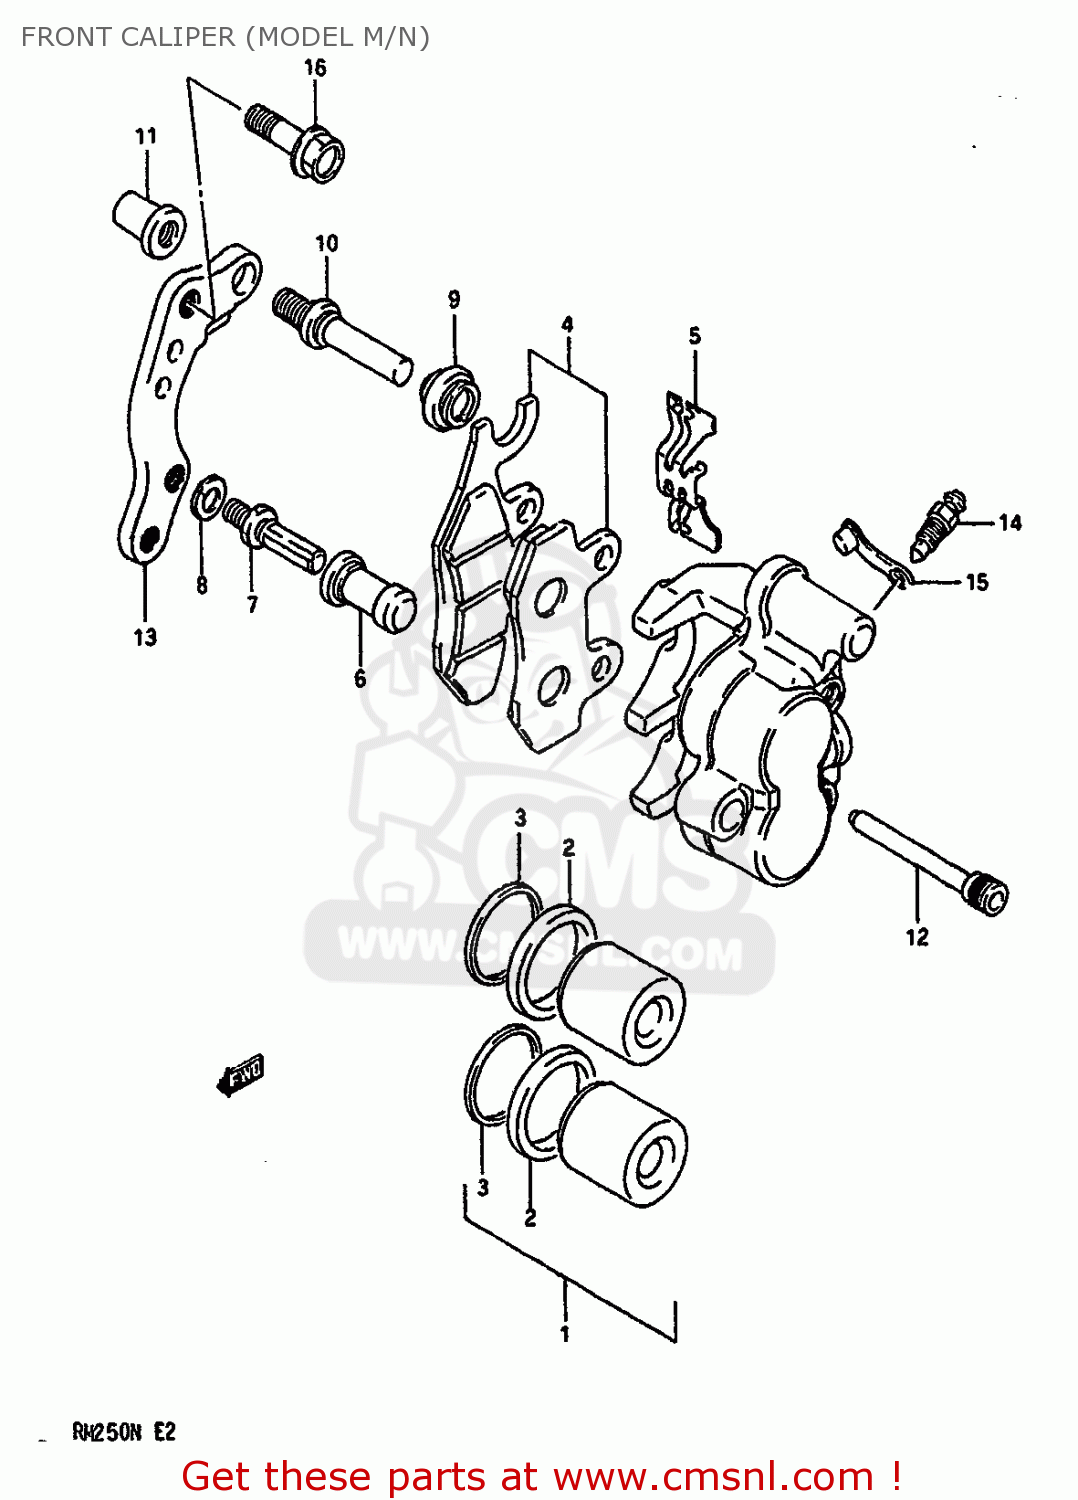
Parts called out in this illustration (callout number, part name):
1	PISTON SET
2	SEAL,PISTON
3	SEAL,DUST
4	PAD SET (NAS)
5	SPRING,PAD
6	BOOT
7	BOLT,PIN
8	WASHER,WAVE
9	BOOT
10	PIN,SLIDE
11	NUT
12	PIN,HOLDER
13	BRACKET
14	BLEEDER
15	CAP,BLEEDER
16	BOLT(8X35)
